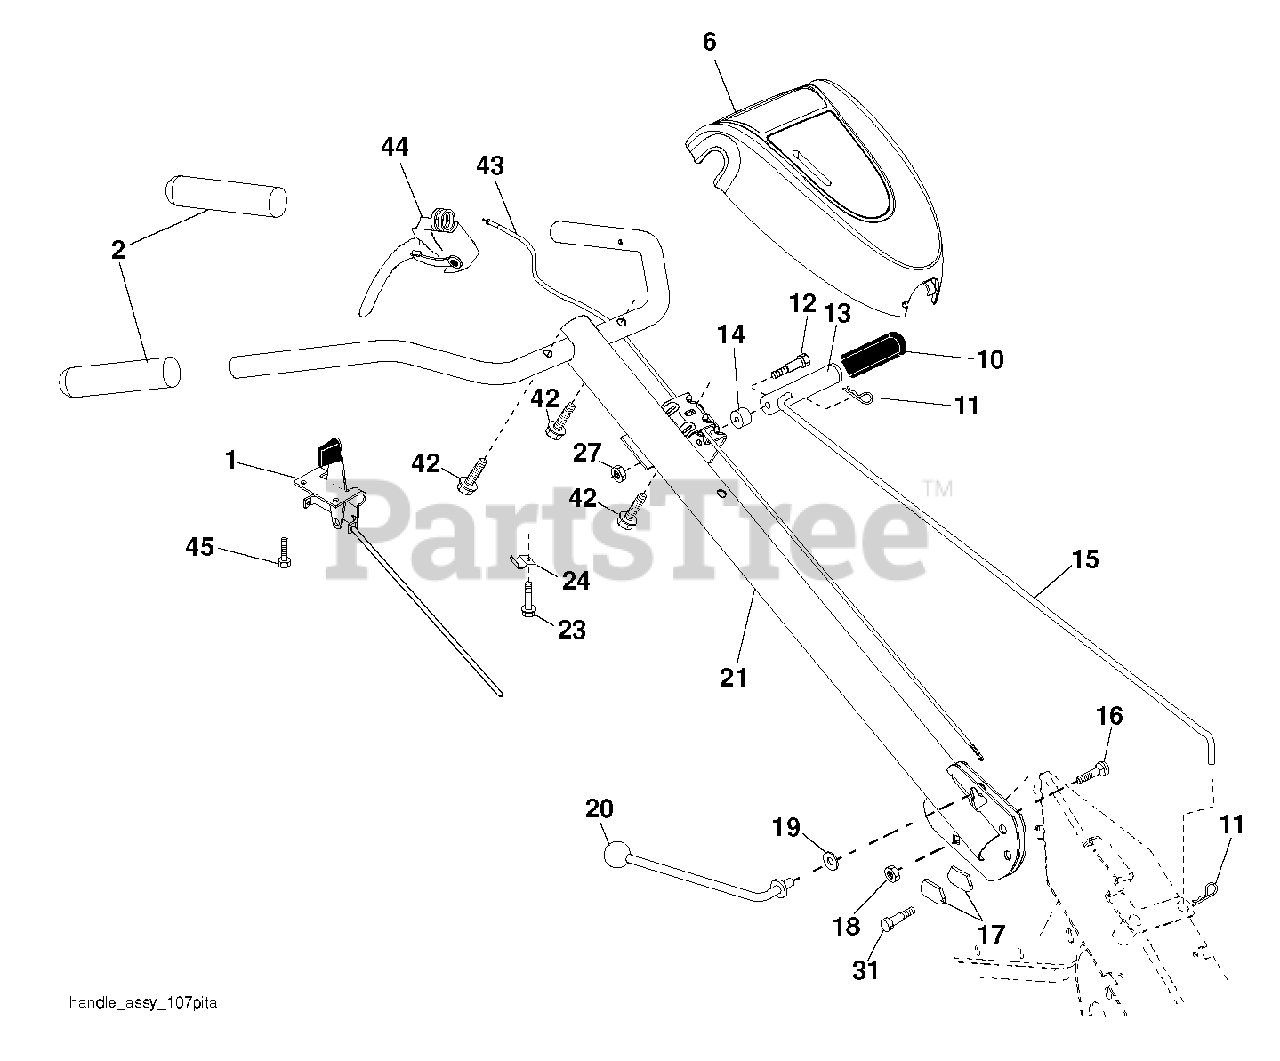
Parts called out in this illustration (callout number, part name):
1	THROTTLE.CONTROL.RT
2	GRIP.1X5.06
10	GRIP T
11	RETAINER M
12	SHOULDER BOLT ST
14	GROMMET.RUBBER.CRT.TILLER
15	ROD, SHIFT
18	LOCKNUT
19	WASHER CRT
20	LEVER.LOCK.CRT
21	Curved Plow Handle Assembly for Tiller, Black
23	TAPPING SCREW
24	CLIP.PLATED
27	NUT T
31	BOLT.PIVOT
42	SCREW.#10 X 0.750.BOS THREAD
45	SCREW.#10 X 0.500
